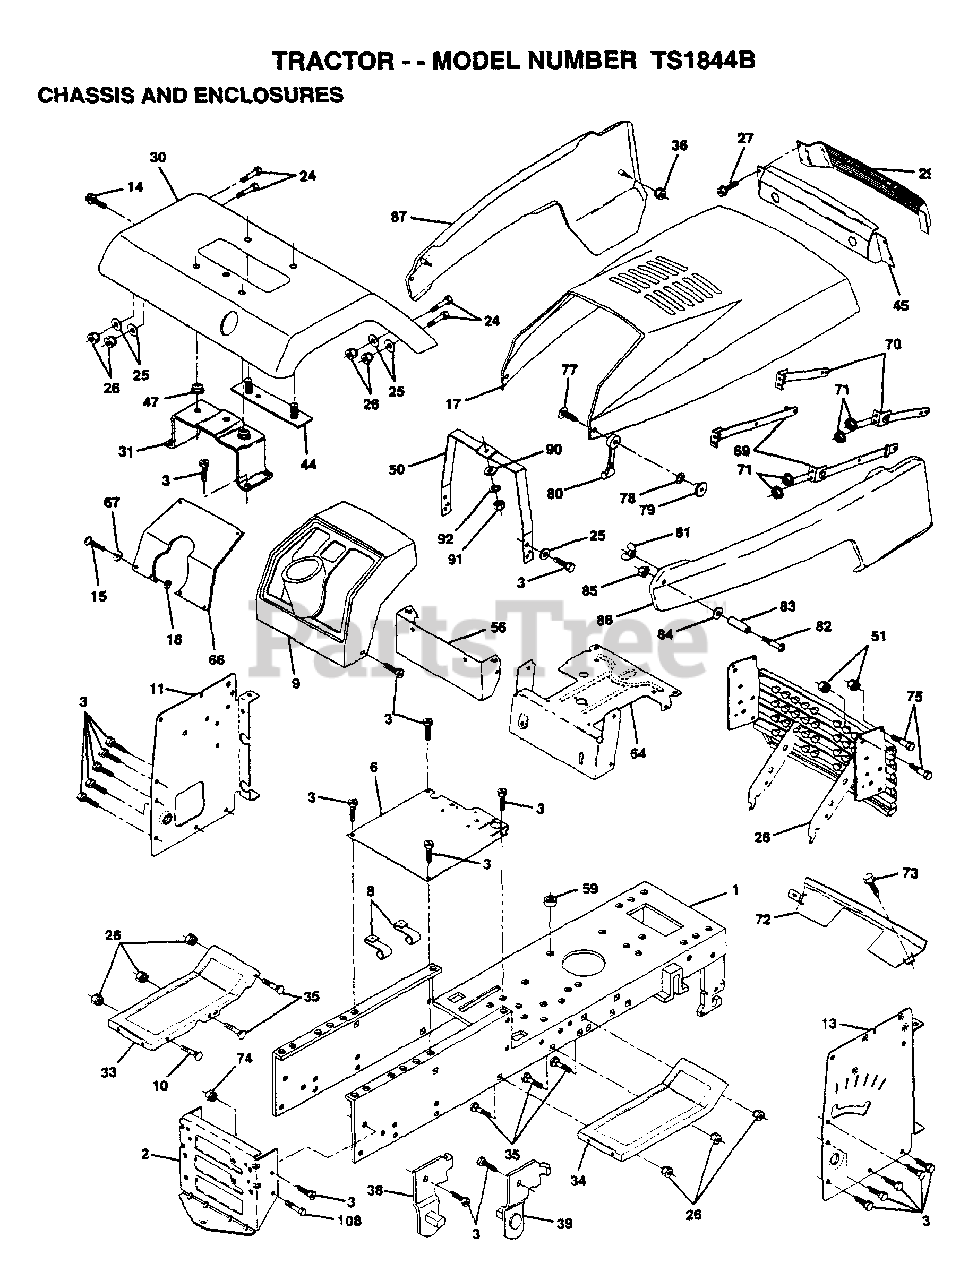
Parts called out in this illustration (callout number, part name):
1	CHASSIS.WLD.11GA
2	DRAW BAR
3	SCREW
8	"CLIP,INSULATOR"
9	DASHBOARD BLACK
11	PANEL.DASH.LH.PNT
13	PANEL.DASH.RH.PNT
14	SCREW LT
15	SCREW
24	BOLT
25	WASHER
26	NUT
29	LENS.BAR.CLEAR
30	FENDER.PNT.
31	BRKT.ASM.FENDER
33	FOOTREST.LH.LT/GT
34	FOOTREST.RH.LT/GT
35	BOLT
36	PAL NUT LT
38	BRACKET ASM LH
39	BRACKET ASM RH
44	STRAP ASM FENDER
47	NUT-PUSH YT
50	DASH.SUPT.YP/HUSQ
56	DASH.EXT.PNT.
66	PLATE SLKSCR YP
67	WASHER
71	NUT HXKEP 1/4X20
72	STRAP.GRILLE.PNT.
73	SCREW CRT
77	SCREW
78	LOCKWASHER
79	WELDNUT
80	HOOD LATCH T
82	SCREW
83	SPACER LT
84	WASHER
86	PANEL SIDE RH
90	WASHER PM
92	LOCKWASHER
